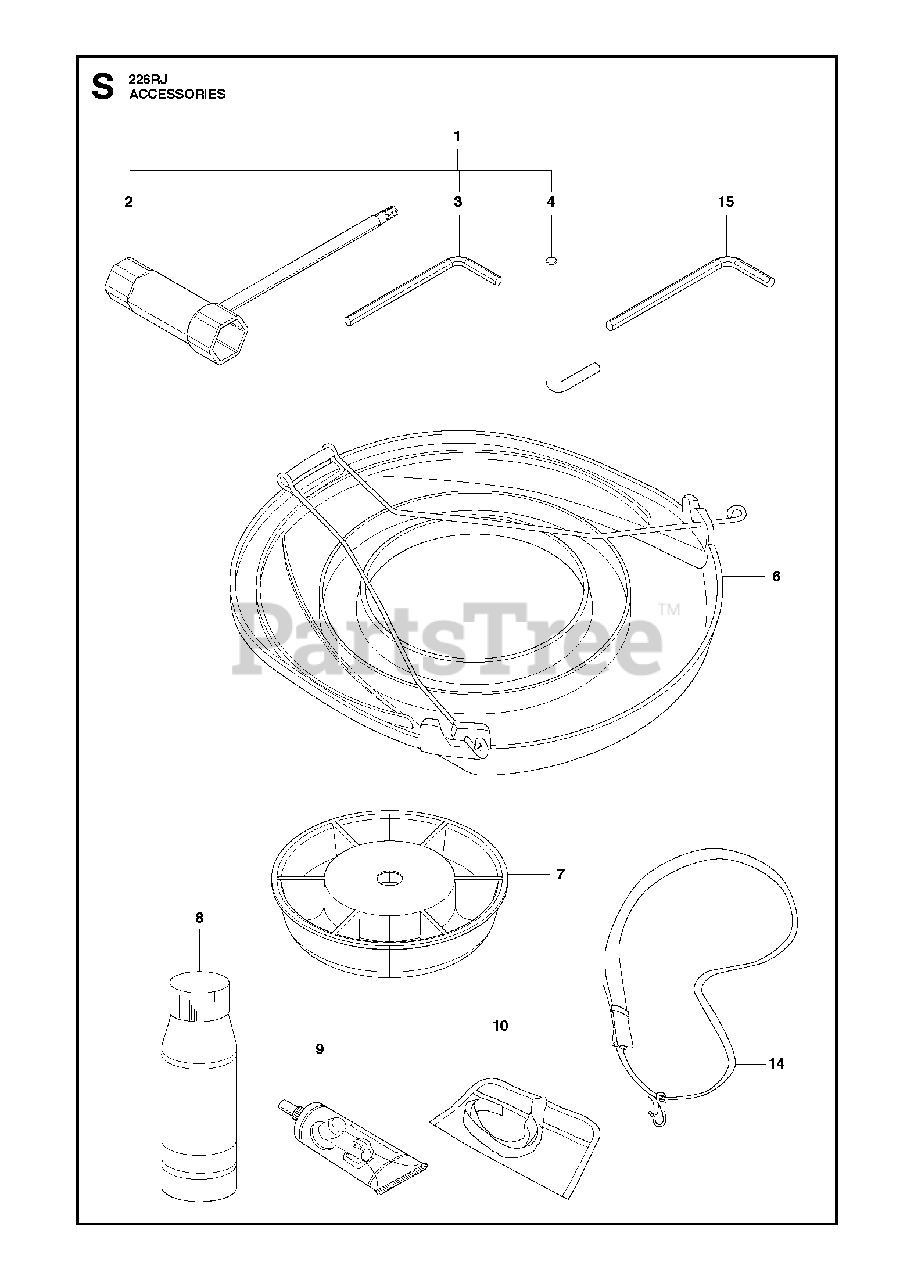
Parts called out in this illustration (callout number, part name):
2	WRENCH
3	WRENCH
4	Bar
6	BLADE GUARD TRANSPORT
7	SUPPORTING CUP
8	Air Filter Oil, HVA 1L Bottle
9	BEVEL GEAR GREASE
14	STRAP
15	Wrench Tool
